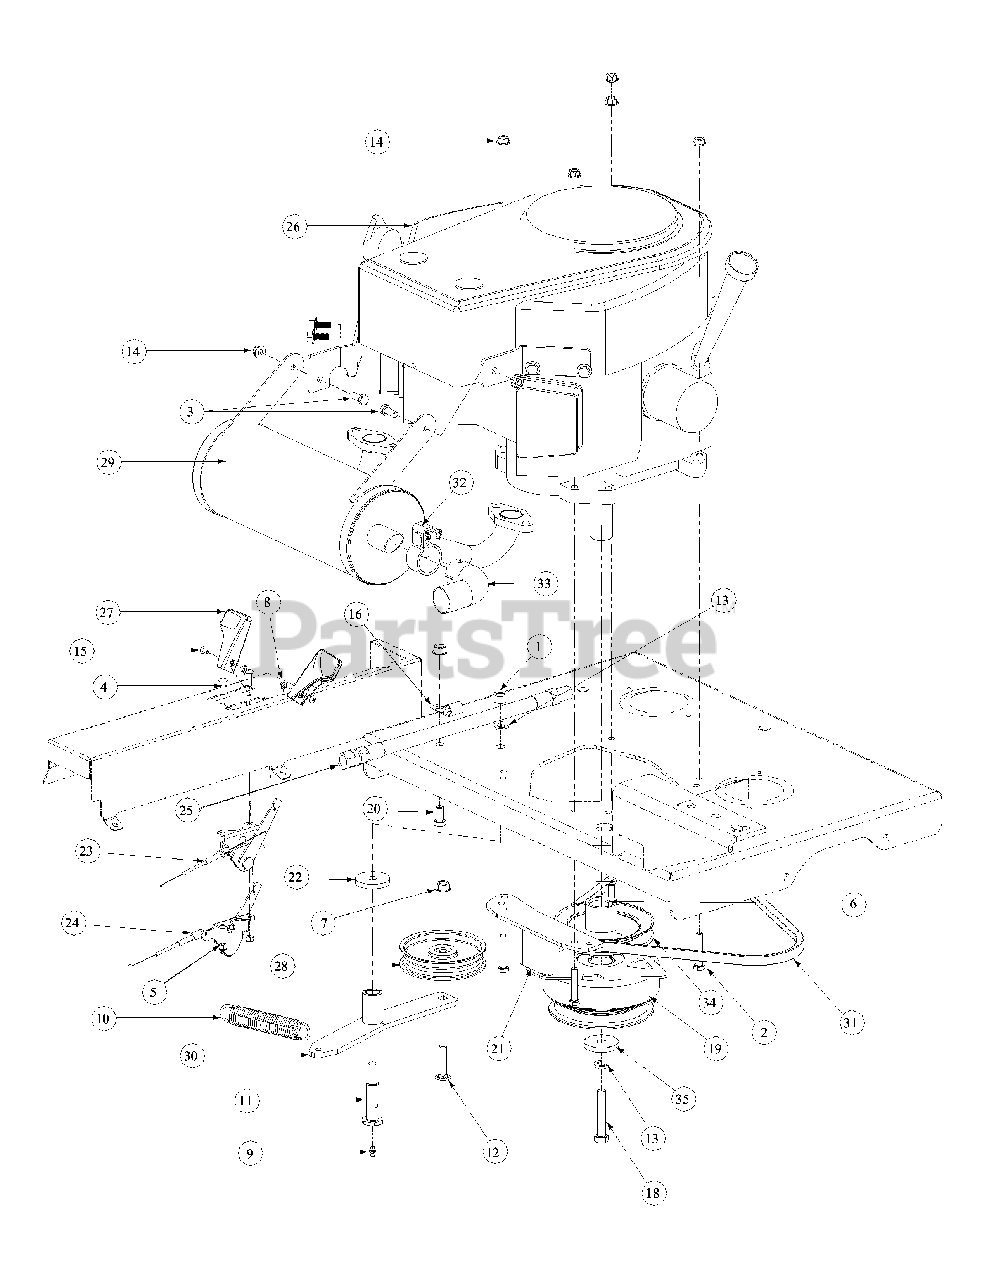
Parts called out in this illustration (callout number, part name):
1	Hex Nut, 7/16-14
2	HHCS, 5/16-18, 1-3/4
3	Hex Cap Screw, 5/16-18 x 3/4
4	Round Hd. Machine Screw, 10-32 x 3/4
5	Lock Nut, Nylon Insert, 10-32
6	Key, 1/4 x 1/4 x 3
7	Flange Lock, Hex Nut, 3/8-16
8	Nut Washer, W/Star, 8-32
9	Grease Fitting, 1/4-28 x 3/16
10	Extension Spring, 1.0 OD x 5.125
11	Shoulder Screw, 7/16-14
12	Hex Carriage Screw, 3/8-16, 1.75
13	Lock Washer, 7/16
14	Hexflange Lock Nut, 5/16-18
15	Machine Screw, 8-32, .375
16	Clip, Heat Shield Cable
18	Capscrew, 7/16-20 x 2.50
19	Clutch Brake, 1.125 ID
20	Hex Cap Screw, 3/8-16, .750
21	Retainer Clutch Assembly, Ogura
22	Flat Washer, 7/16 ID x 1.75 OD x .25
23	Choke, Control Cable, 43.0
24	Throttle, Control Cable, 39.0
25	Oil Drain Hose
26	19HP Twin Engine, Kawasaki
26	23HP Kawasaki Engine
27	Control Throttle Knob
28	Flat Pulley with Flanges
29	Muffler Accessory, Kawasaki
30	Engine Idler Arm Assembly
31	V Belt, A Section x .47.3
32	Tube Clamp, 1.375
33	Muffler Accessory Exhaust Tube
34	Pump Drive Pulley
35	Flat Washer, 7/16 ID x 1.75 OD x .25
